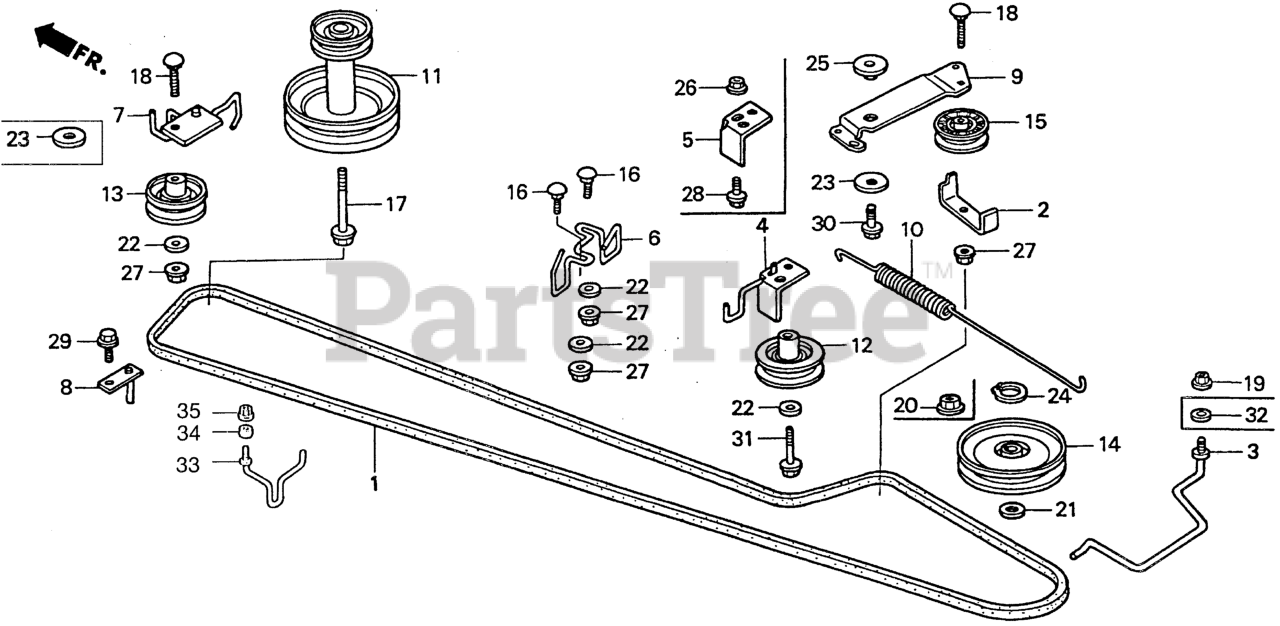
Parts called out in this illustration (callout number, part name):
1	V-BELT (A-102)
2	STOPPER A, BELT
3	STOPPER B, BELT
4	STOPPER C, BELT
6	STOPPER D, BELT
7	STOPPER E, BELT
8	STOPPER F, BELT
9	ARM, TENSIONER
10	SPRING, BELT TENSIONER
11	PULLEY, ENGINE
12	ROLLER A, TENSIONER
13	ROLLER B, TENSIONER
14	PULLEY ASSY., TRANSMISSION
15	ROLLER, TENSION
16	BOLT, SPECIAL (8X20)
17	BOLT, FLANGE (7/16")
18	BOLT, PAN (8X50)
19	NUT, FLANGE (8MM)
22	WASHER (8MM)
23	WASHER (8.5X42X3)
24	CIRCLIP, EX. (5/8")
25	COLLAR, TENSIONER ARM
27	NUT, FLANGE (8MM)
29	BOLT, FLANGE (8X16)
30	BOLT, FLANGE (8X25)
31	BOLT, FLANGE (8X60)
